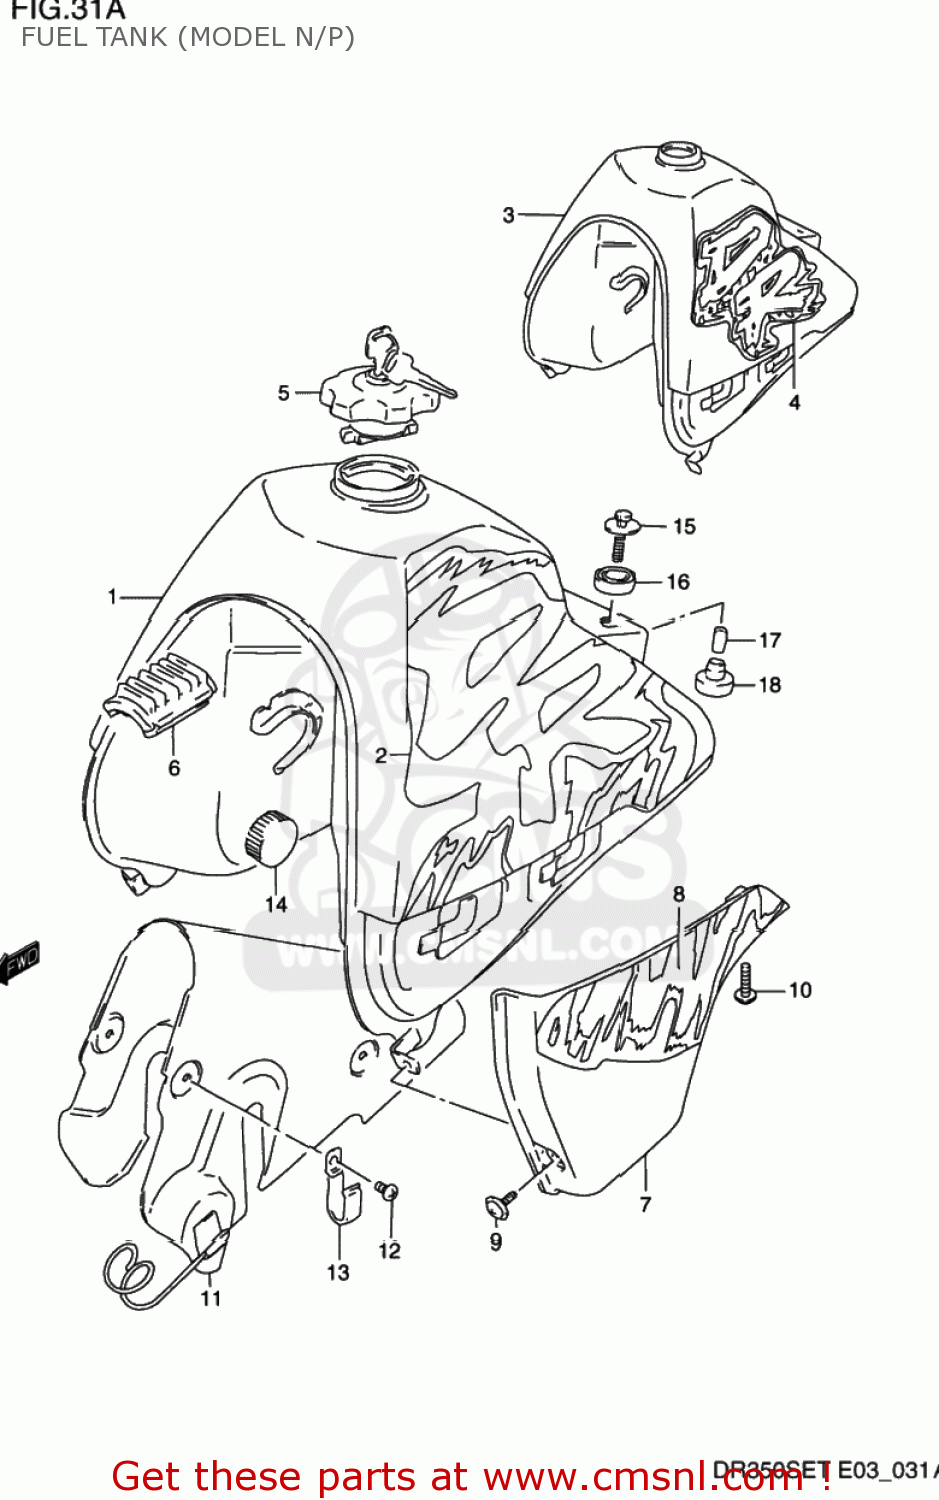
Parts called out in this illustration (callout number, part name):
1	TANK ASSEMBLY,FUEL
2	TAPE SET,FUEL TANK
3	TANK ASSEMBLY,FUEL
4	TAPE SET,FUEL TANK
5	CAP SET,FUEL TANK
6	CUSHION.UPPER
7	COVER,FUEL TANK,R
8	TAPE,FUEL TANK STRIPE
9	SCREW
10	SCREW(6X12)
11	SHIELD,FUEL TANK
12	SCREW
13	CLAMP(L:65)
14	CUSHION
15	BOLT
16	CUSHION
17	SPACER
18	CUSHION
